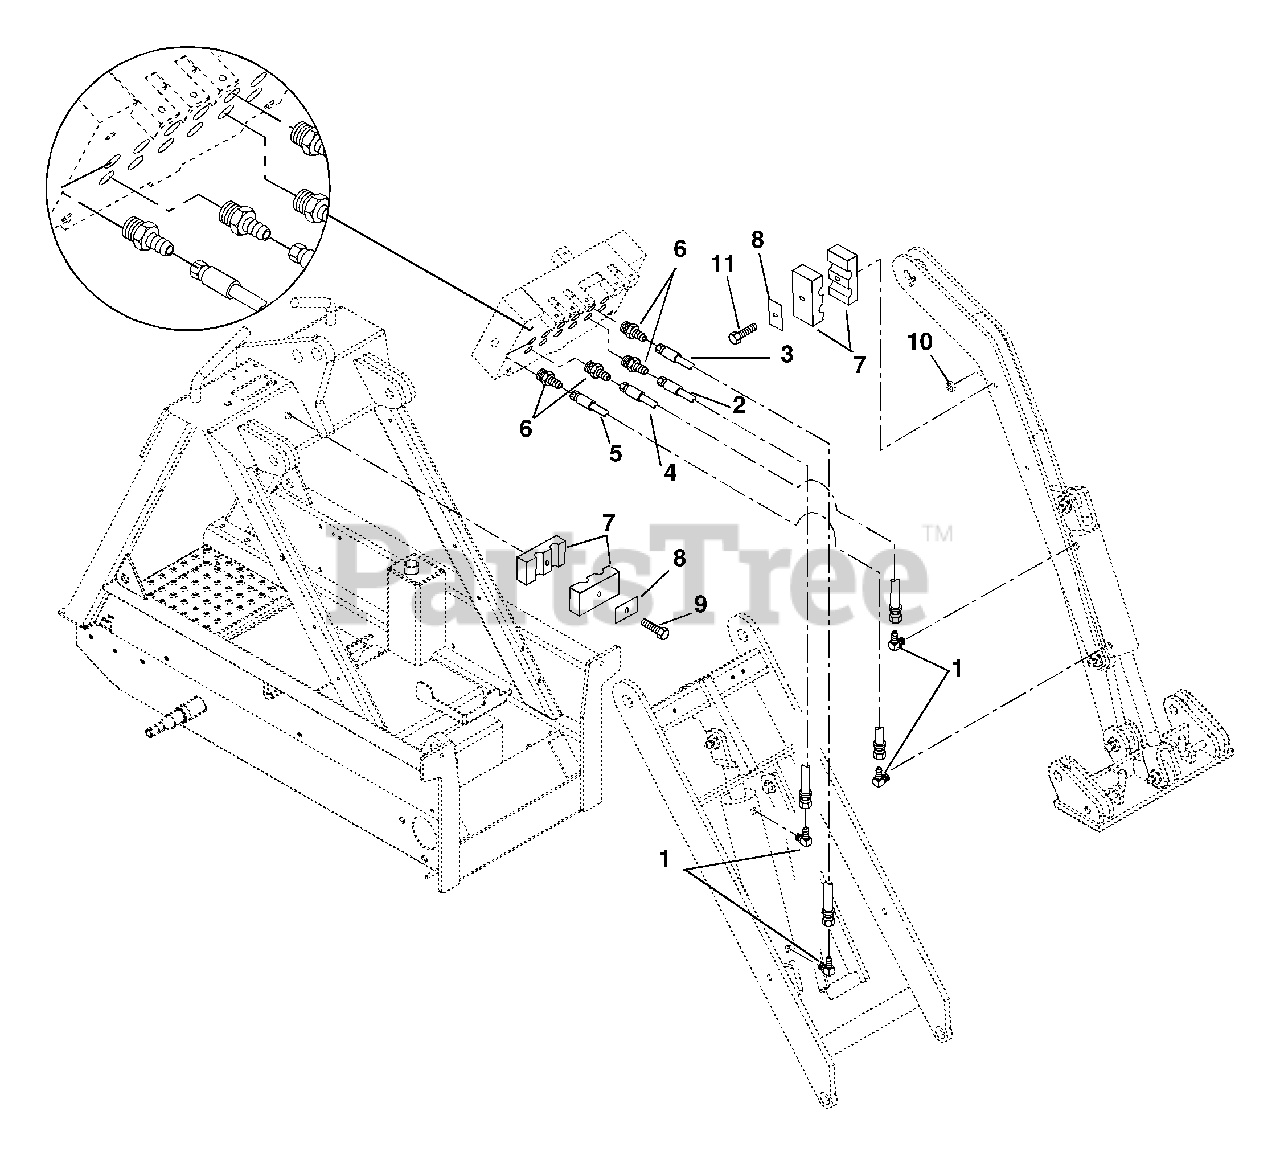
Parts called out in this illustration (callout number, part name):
1	Adapter-Elbow 90 Degree .750-16M x .562-18M
2	Hose-Hydraulic Valve Bank to Lift Cylinder
3	Hose-Hydraulic Valve Bank to Lift Cylinder
4	Hose-Hydraulic Valve Bank to Crowd Cylinder
5	Hose-Hydraulic Valve Bank to Crowd Cylinder
6	Adapter-Straight .500-14 x .562-18M
7	Clamp-Dual Hose .375 I.D.
8	Plate-Cover
9	Bolt-Hex M8 x 1.25 x 55
10	Nut-Locking-Nylon M10-1.5
11	Bolt, Hex M8-1.25 x 110
